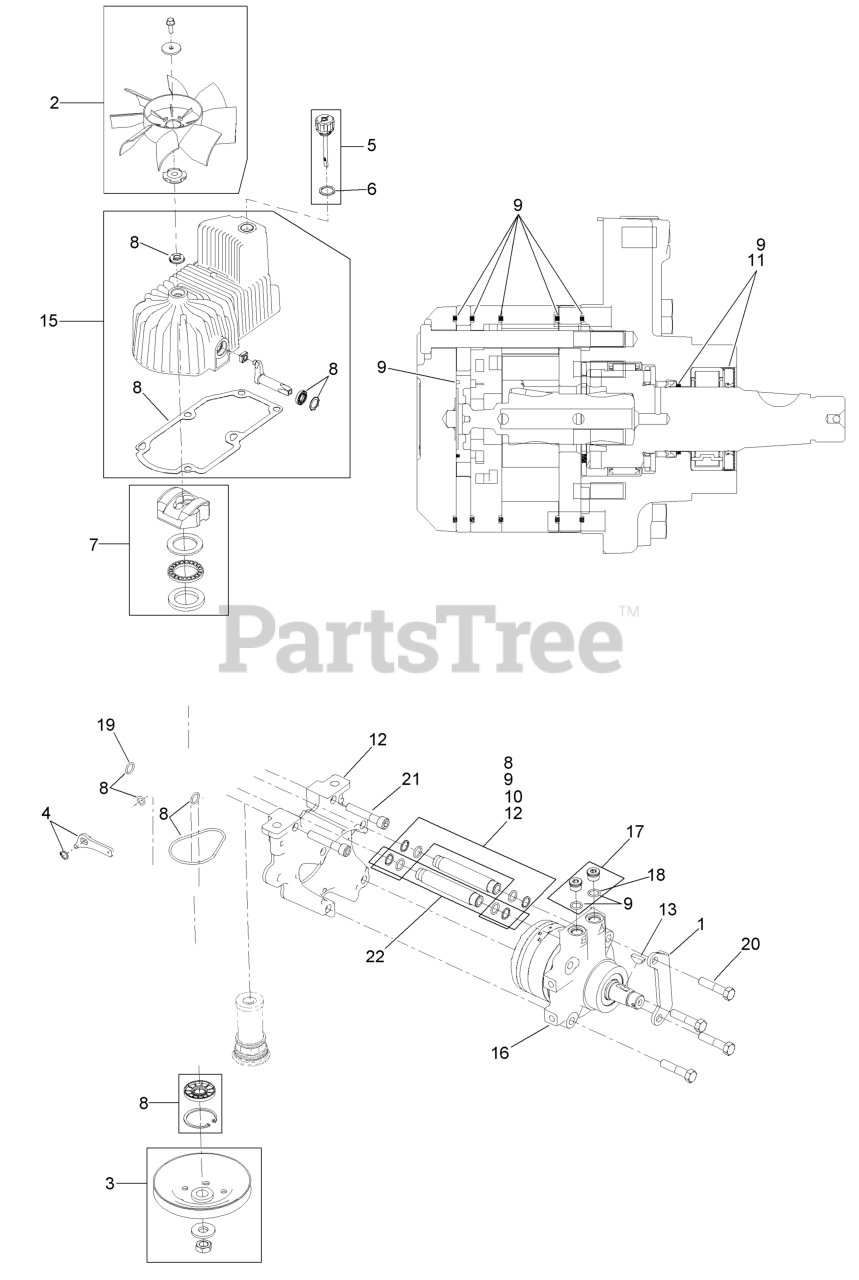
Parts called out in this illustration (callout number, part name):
1	MOUNT-SHOE, HORSE
2	FAN KIT
3	PULLEY KIT
4	HANDLE-BYPASS VALVE, HYDRO
5	DIPSTICK-HYDRO W/GASKET
6	GASKET-DIPSTICK, HYDRO
7	SWASH BLOCK KIT
8	PUMP SEAL KIT
9	MOTOR SEAL KIT
10	TUBE SEAL KIT
11	OUTPUT SHAFT SEAL KIT
12	NOSE CUP-UHT
13	KEY-WOODRUFF
15	HOUSING-HYDRO, RH
16	MOTOR-HYDRAULIC RH 240CC
17	MAGNETIC PLUGS SERVICE KIT
19	O-RING-CHECK VALVE
20	SCREW HH
21	SCREW-HSH
22	HYDRAULIC TUBE KIT
